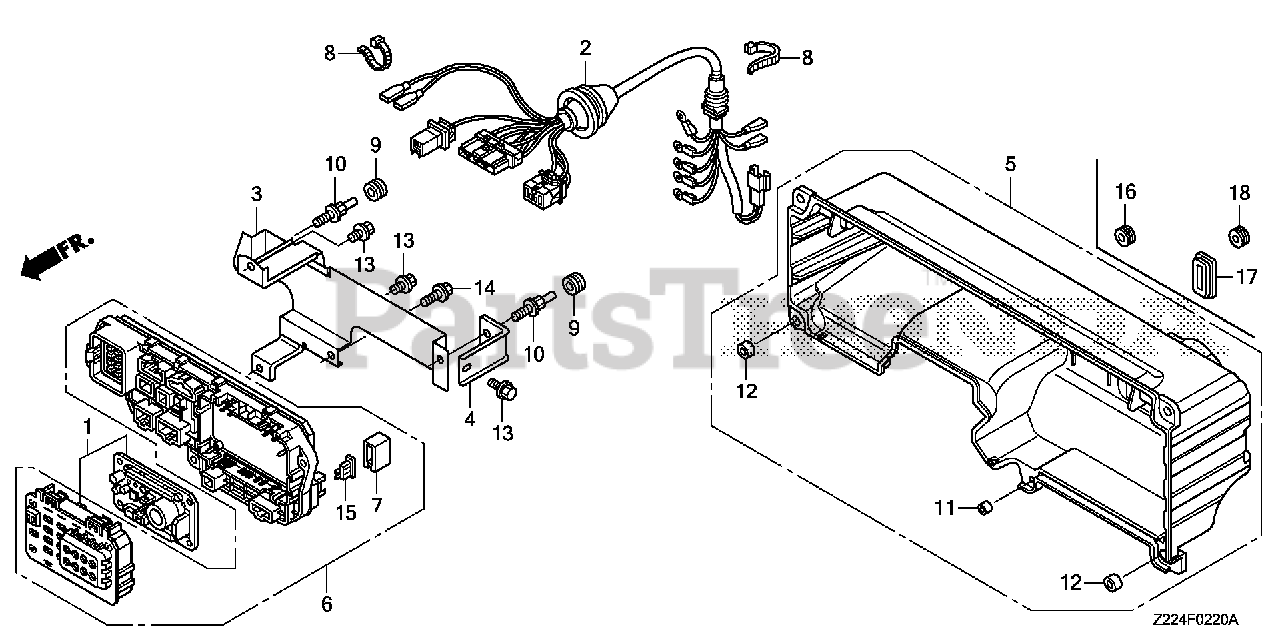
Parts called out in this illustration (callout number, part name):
1	COVER ASSY., AUTOMATIC VOLTAGE REGULATOR
2	WIRE HARNESS ASSY., GENERATOR (EB-A)
3	BRACKET, JUNCTION BOX
4	PLATE, JUNCTION BOX
5	CASE, CONTROL PANEL
6	BOX ASSY., JUNCTION
7	COVER, FUSE
8	TIE, CABLE (C)
9	GROMMET, SEAT LOCK LEVER
10	BOLT, FLANGE (6X18)
11	COLLAR, CONTROL CASE
12	COLLAR, CONTROL CASE
13	BOLT, FLANGE (6X10)
14	BOLT, FLANGE (6X14)
15	FUSE, BLADE (20A)
